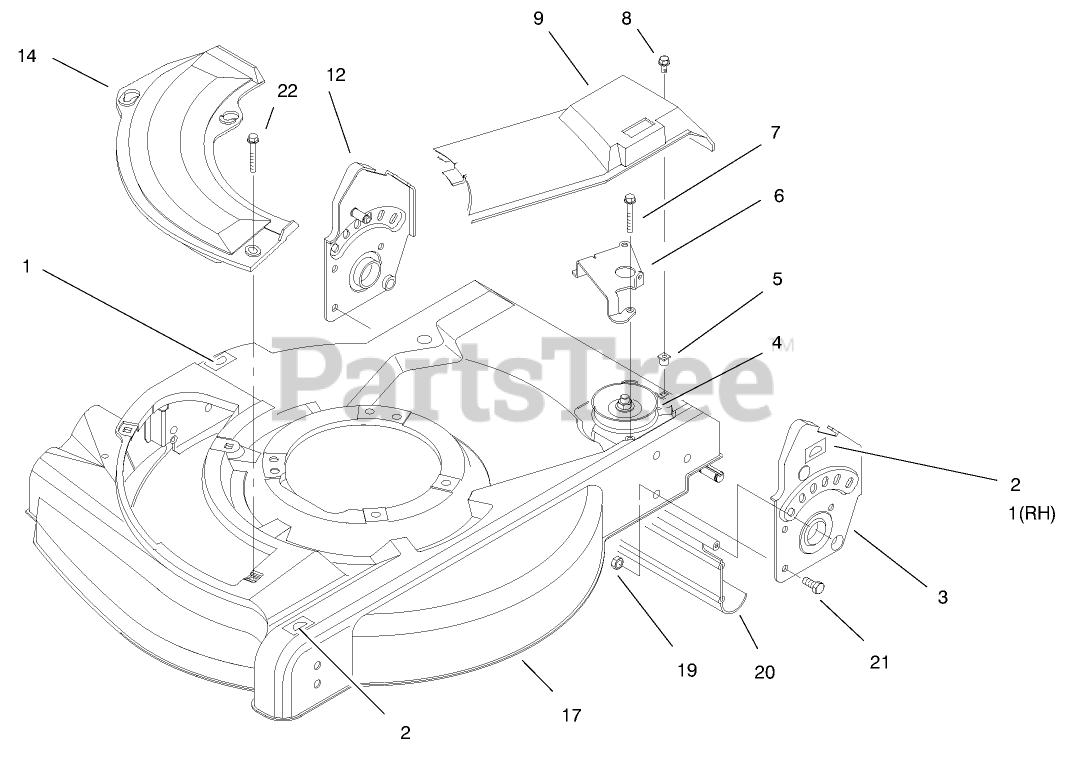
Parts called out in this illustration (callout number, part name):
1	DECAL-HOC, RH
2	DECAL-HOC, LH
3	HANDLE BRACKET ASM-LH
4	Gear Case
5	NUT-CLIP
6	Guide-Transmission
7	SCREW-HWHTF
8	SCREW-TAP
9	COVER-DRIVE
12	HANDLE BRACKET ASM-RH
14	PLATE-OPENING, CHUTE
17	Housing & Baffle ASM (Incl. Ref. #1-2, 6, & 10 pg. 1)(Incl. Ref. #1-2 pg. 2)
19	NUT-LOCK, NI
20	SHIELD-TRAILING
21	SCREW-HH
22	SCREW-HWH
